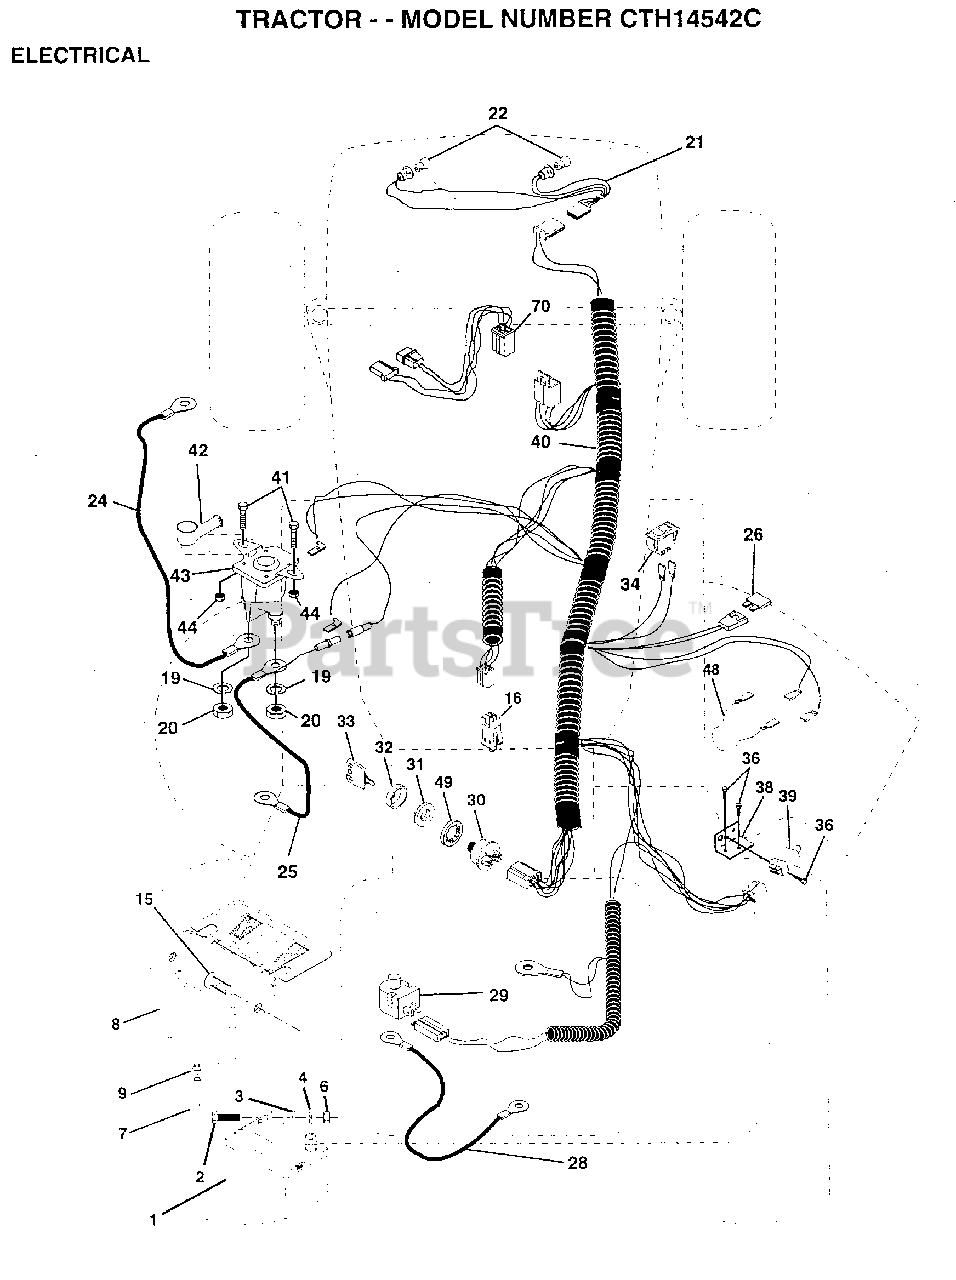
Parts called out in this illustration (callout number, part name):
2	BOLT LT
3	WASHER
4	LOCKWASHER
7	TUBE T
9	HOSE CLAMP T
15	FASTNER.SNAP-IN
16	SWITCH INTERLOCK
20	NUT
21	"HARNESS,LIGHT SOC"
22	HEADLAMP BULB
24	CABLE.BTRY.6GA.RD
25	CABLE.BTRY.6GA.38
26	FUSE HYT
28	CABLE T
29	SWITCH SEAT
32	COVER KEY SWITCH
33	KEY MLD GEN DELTA
34	SWITCH LT
35	BRACKET LT
36	SCREW
38	BRACKET SWITCH IN
39	SWITCH INTERLOCKT
40	HARNESS.IGN.DASH.
41	BOLT HXHD FIN
44	NUT HXKEP 1/4X20
48	ADAPTER AMMETER
49	WASHER PINNED
70	HARNESS.ENG.DUAL
